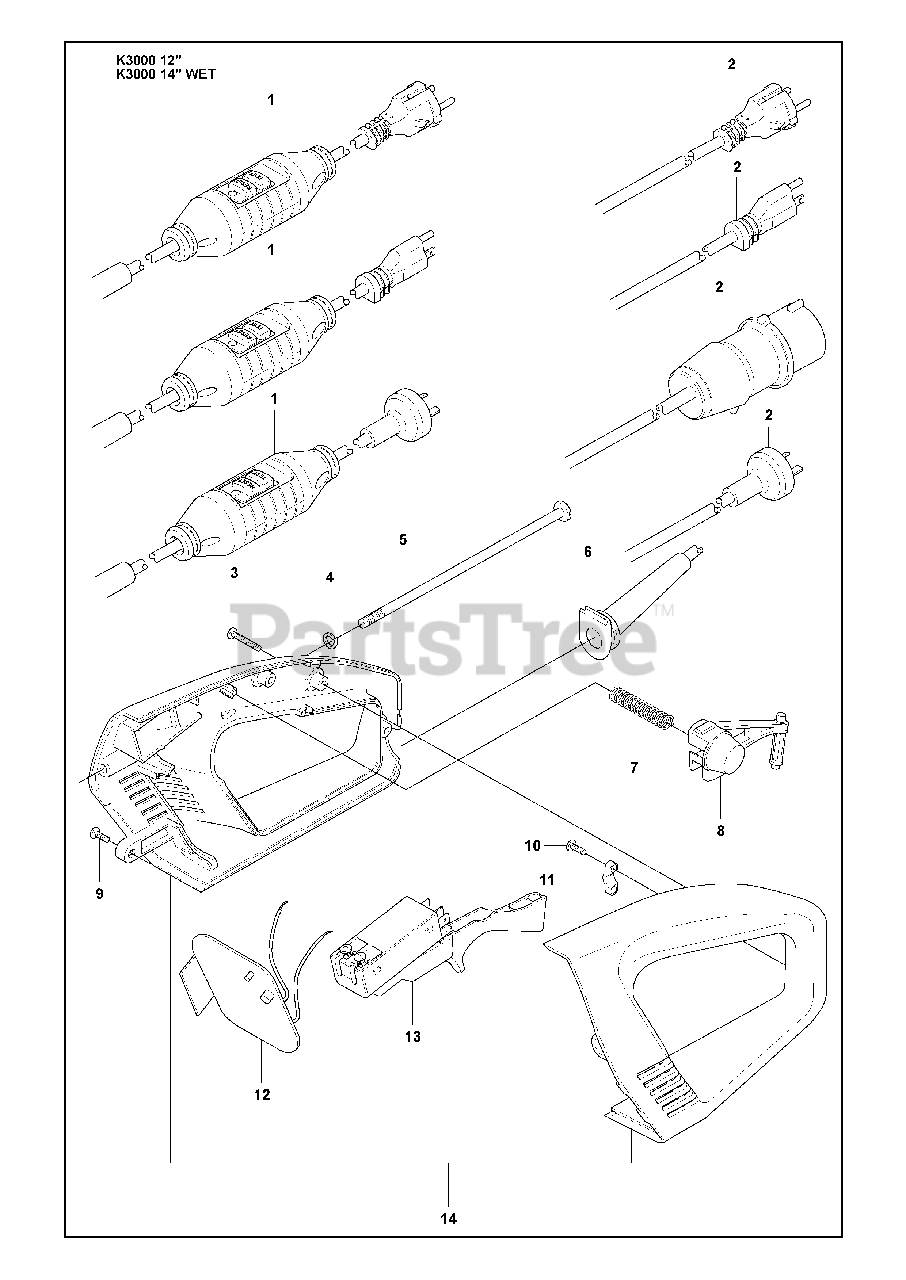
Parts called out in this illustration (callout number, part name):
1	Cable Assy
2	Cable Cpl
6	Cable Sleeve
7	Spring
8	Locking Button
12	Printed Circuit Assy
14	Handle Assy
